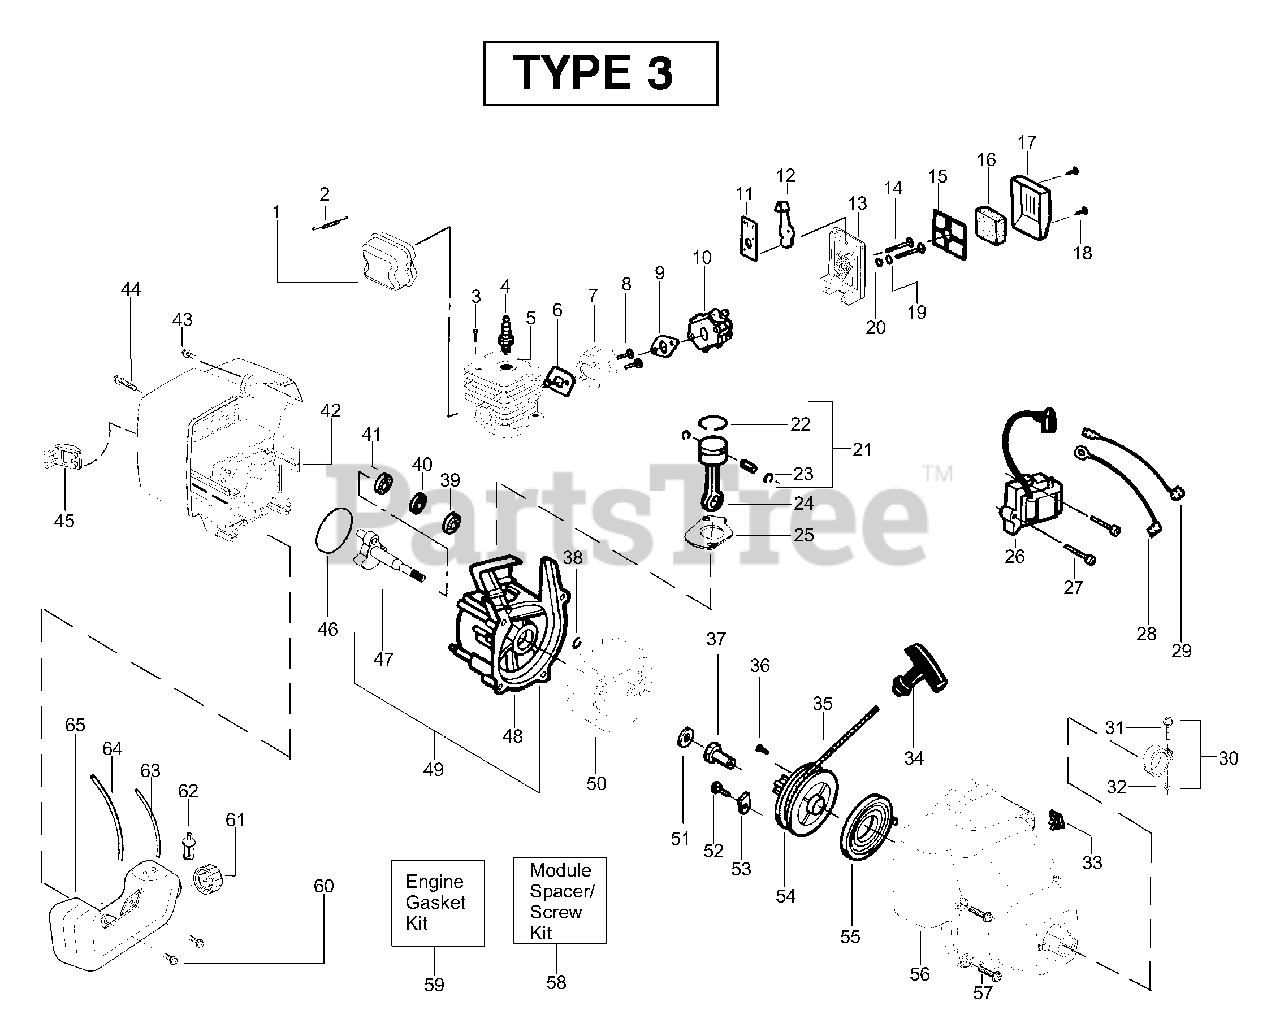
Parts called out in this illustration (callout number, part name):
1	Kit - Muffler
2	Spring-Muffler
3	Screw-Cylinder
4	Spark Plug (RCJ-6Y)
5	Kit - Cylinder
6	Gasket-Cylind./Carb.
7	Adapter-Carb.
9	Gasket-Carb.
10	Kit - Carburetor Ass'y (Wa-226)
10	Kit - Carburetor Ass'y (WT-631)
11	Choke Plate Mounting
12	Shutter-Choke
15	Plate - Filter Support
16	Foam-Air Filter
17	Cover-Air Filter
19	Spacer-Choke
21	Kit - Piston
22	Piston Ring
23	Retainer-Piston Pin
24	Assy-Connecting Rod
25	Gasket-Cylinder
26	Ignition Module
28	Assy-Ground Wire
29	Assy-Leadwire
30	Assy-Nose Cone Clamp
31	Screw-Nose Cone
32	Nut-Nose Cone
33	Kit-Switch
34	Handle-Starter
35	Kit - Rope
37	Coupling-Drive
38	Retain. Ring-C'shaft
39	Outer Bearing
40	Kit-C'case Seal
41	Inner Bearing
42	Kit-Shroud
44	Screw
45	Guard-Muffler
46	O-Ring-C'case/Shrd
47	Assy-Crankshaft
48	Kit-Crankcase
49	Assy-C'case & C'shaft
50	Assy-Flywheel
51	Washer-Flat
53	Retainer-Can
54	Kit-Starter Pulley
55	Spring-Starter
56	Kit-Fan Hsg
57	Screw
58	Kit-Module Spacer & Screws
59	Kit-Engine Gasket
60	Retainer
61	Assy-Fuel Cap
62	Assy-Fuel Pickup
63	Kit-Fuel Line (Small)
64	Kit-Fuel Line (Large)
65	Assy-Fuel Tank
